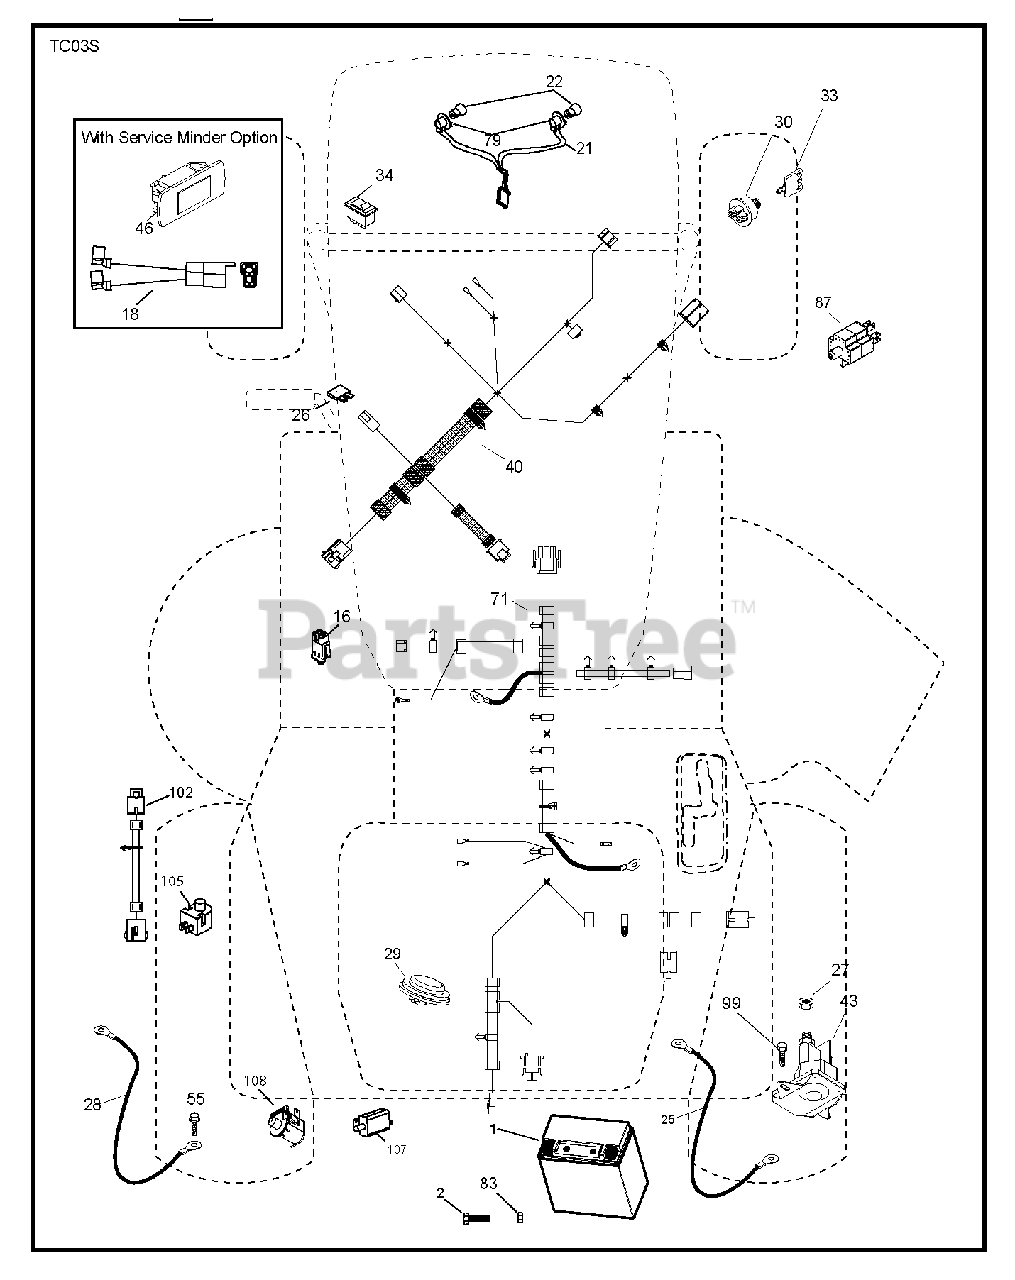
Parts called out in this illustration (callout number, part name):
16	SWITCH INTERLOOK PUSH-IN
21	HARNESS.LIGHT W/4152J BULBS
22	LIGHTBULB
26	FUSE 20AMP
27	NUT
29	SWITCH.SEAT.DELTA.OPC.
30	SWITCH.IGN.DELTA.W.LGH.ROS
33	KEY.CHAIN.BLISTER.PACK.GEN.INT
34	SWITCH LT
43	SOLENOID.W/BRASS.PLUNG
46	GUAGE.SRVCMNDR.HRMTR.
55	SCREW 5/16"
79	BULB HOLDER ASM.
99	SCREW
105	REVERSE SWITCH
108	SWITCH.SNAPMOUNT.NC
